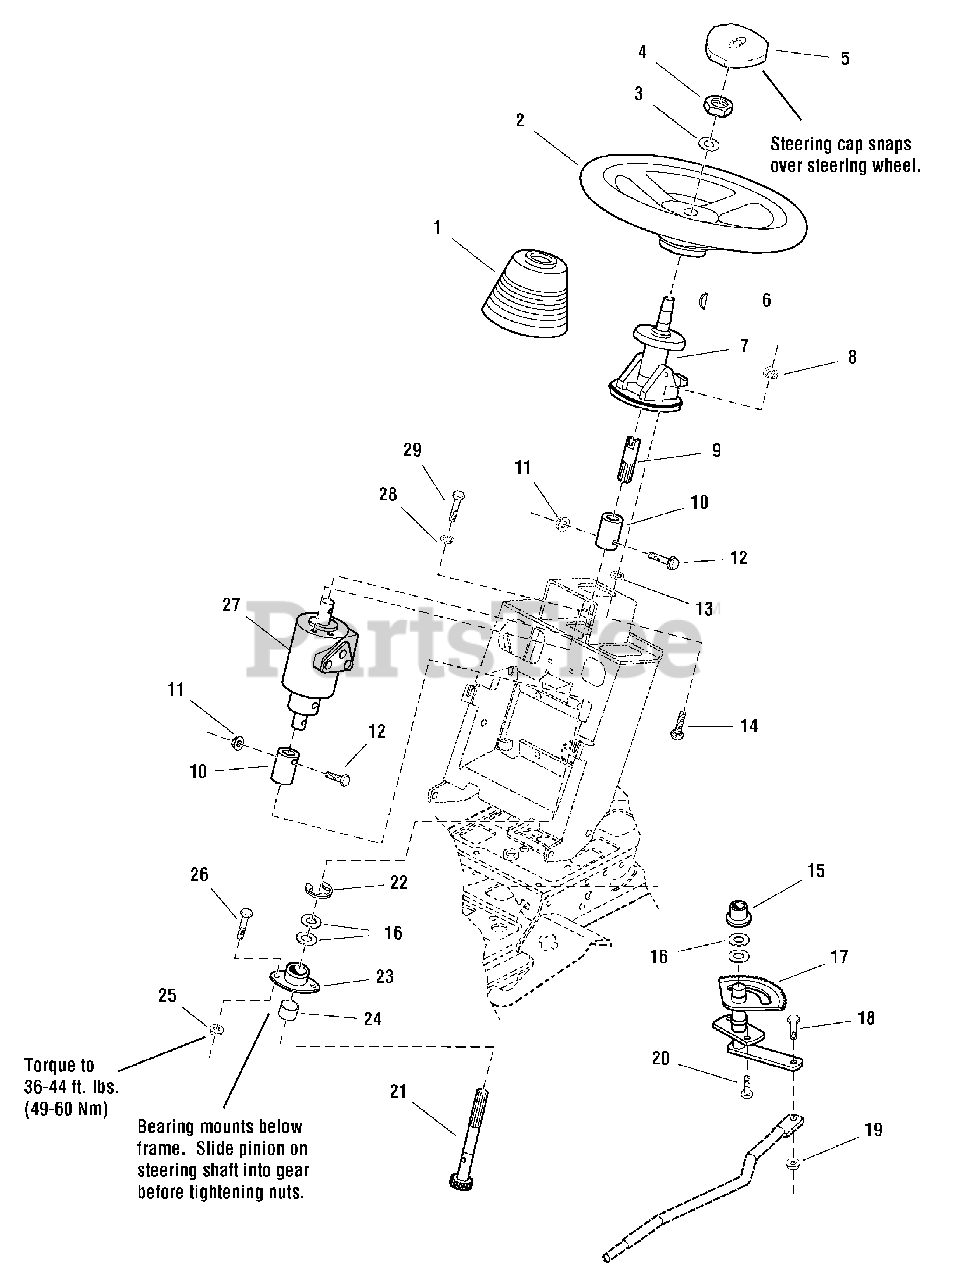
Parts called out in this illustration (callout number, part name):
1	BOOT, Tilt Steering Unit
2	STEERING WHEEL, Tapered, Shaft with Tilt
3	WASHER, 5/8
4	NUT, Hex Lock, ESNA Light, 5/8-18, Thin
5	CAP, Steering Wheel, Simplicity
6	KEY, Woodruff
7	TILT STEERING UNIT
8	NUT, Hex KEPS, 1/4-20
9	ADAPTER, 2-13/16 Long
10	COUPLER, 2-3/8 Long
11	NUT, Hex Lock, ESNA Light, 5/16-18
12	CAPSCREW, Hex Head 5/16-18 x 1-3/4
13	NUT, Push
14	CARRIAGE BOLT, 1/4-20 x 1-1/4
15	BUSHING, Nylon
16	WASHER, 3/4
17	GEAR &, Shaft ASSEMBLY, Steering
18	CAPSCREW, Hex Head, 3/8-16 x 1-1/4
19	NUT, Hex Flange Two-Way Lock, 3/8-16
20	CAPSCREW, Hex Washer Head Taptite, 5/16-18 x 3/4
21	SHAFT & PINION ASSEMBLY, Steering Power wtih Tilt
22	RING, Clipring Extension
23	BEARING, 3/4 x 1-11/16
24	SPACER, 3/8" Long
25	NUT, Hex Flange Whiz Lock, 3/8-16, Small
26	CARRIAGE BOLT, 3/8-16 x 3/4
27	GENERATOR, Torque, Power Steering Unit
28	LOCKWASHER, Spring, 5/16
29	CAPSCREW, Hex Head, 5/16-18 x 3/4
